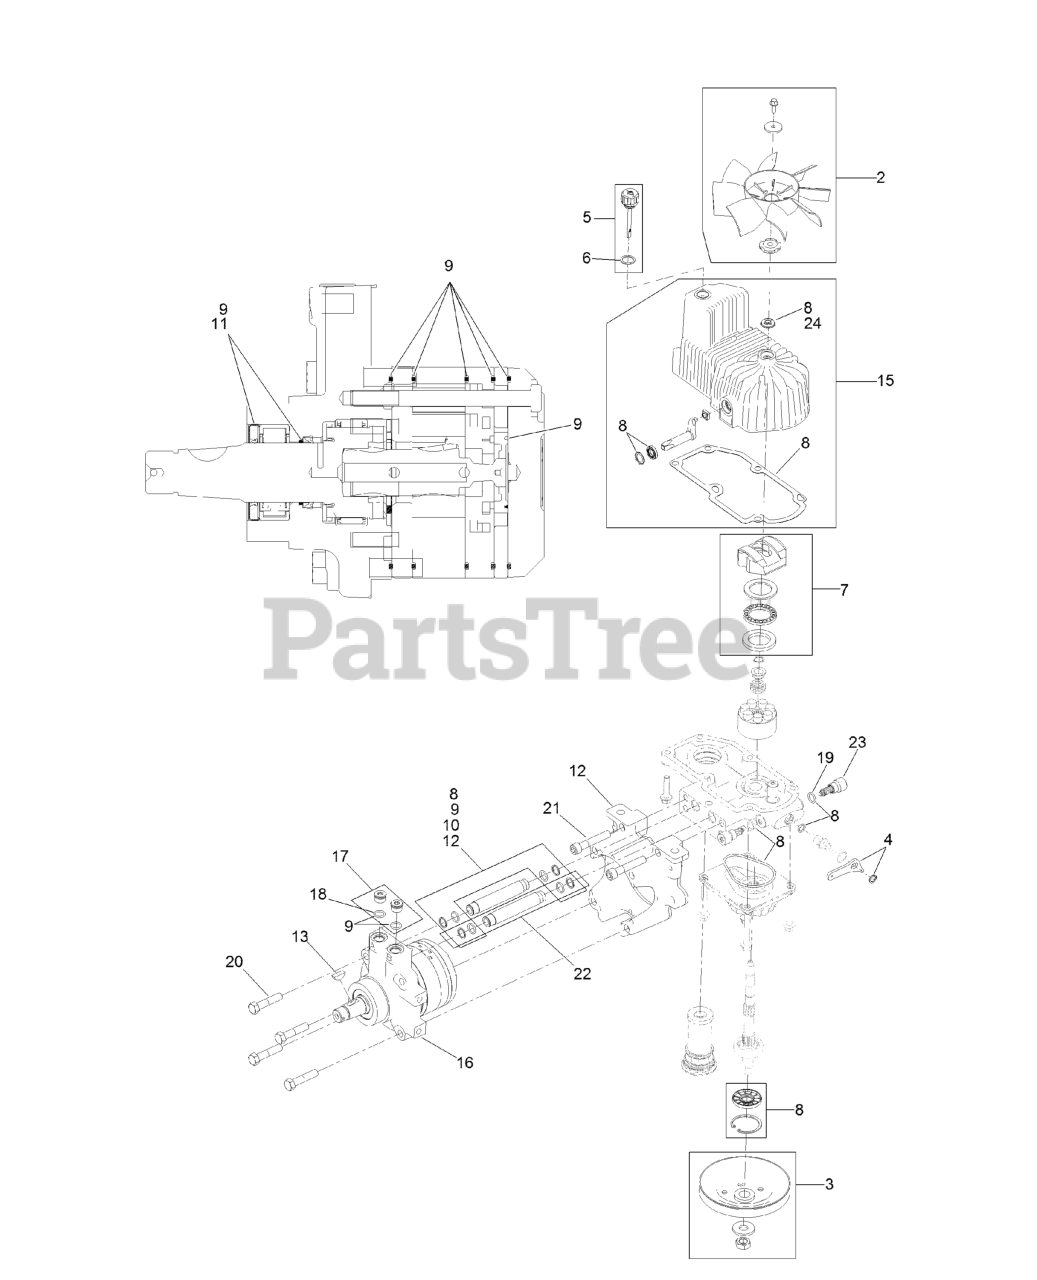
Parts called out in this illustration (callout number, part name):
2	FAN KIT
3	PULLEY KIT
4	HANDLE-BYPASS VALVE, HYDRO
5	DIPSTICK-HYDRO W/GASKET
6	GASKET-DIPSTICK, HYDRO
7	SWASH BLOCK KIT
8	PUMP SEAL KIT
9	MOTOR SEAL KIT
10	TUBE SEAL KIT
11	OUTPUT SHAFT SEAL KIT
12	NOSE CUP-UHT
13	KEY-WOODRUFF
15	HOUSING-HYDRO, LH
16	MOTOR-HYDRAULIC LH 240CC
17	MAGNETIC PLUGS SERVICE KIT
19	O-RING-CHECK VALVE
20	SCREW HH
21	SCREW-HSH
22	HYDRAULIC TUBE KIT
23	SHOCK VALVE, 12CC HYDRO
24	SEAL-FAN DRIVE
25	PULLER-PULLEY
26	ROTATING KIT
